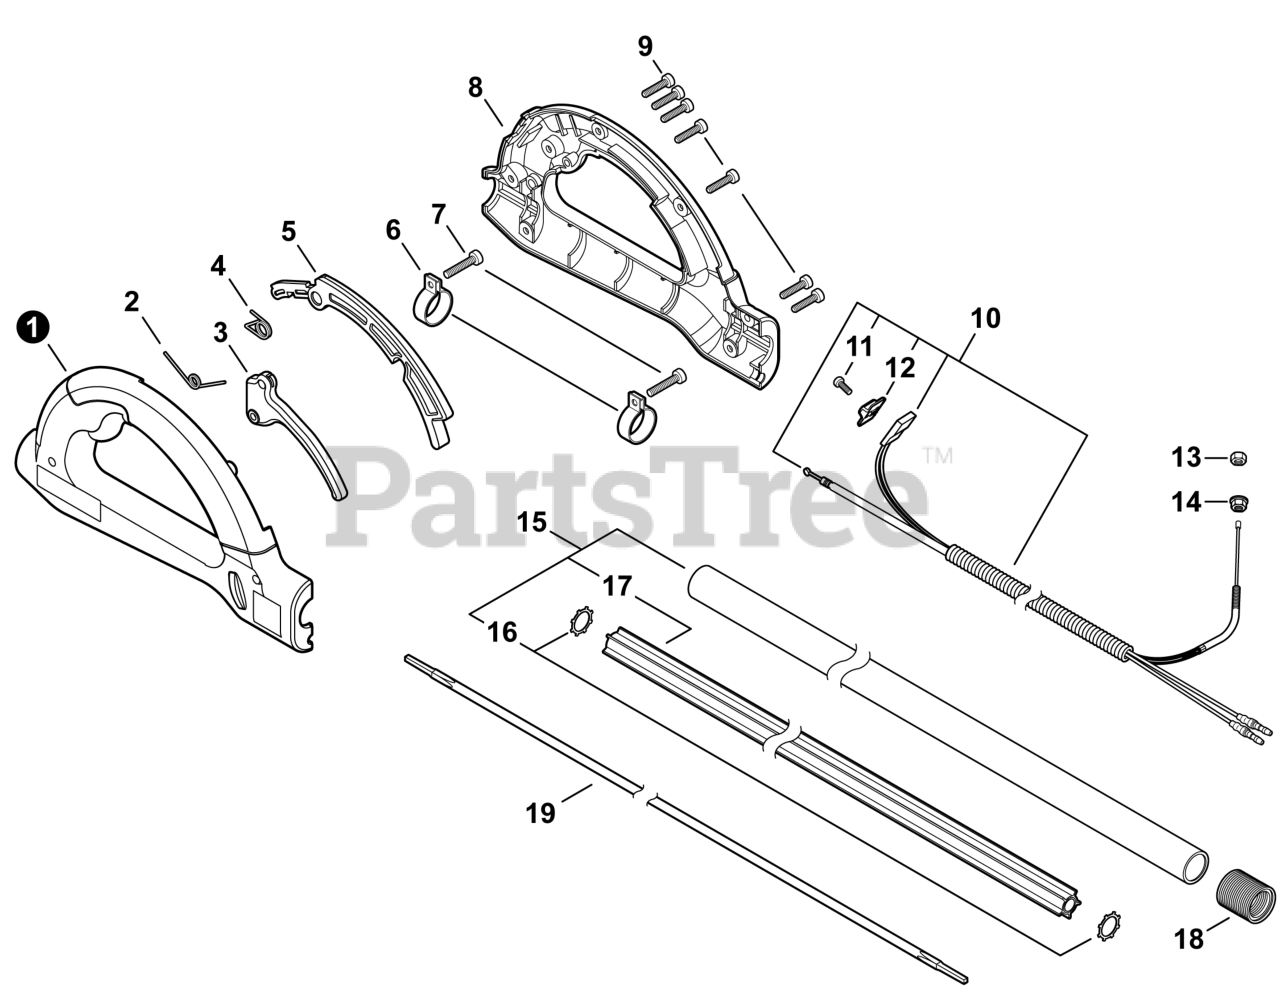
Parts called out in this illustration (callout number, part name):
1	BODY, HANDLE - LEFT
2	SPRING, TORSION
3	TRIGGER, THROTTLE
4	SPRING, TORSION
5	LOCKOUT, THROTTLE
7	BOLT, TORX 5x16
8	BODY, HANDLE - RIGHT
9	BOLT, TORX 5x16
10	CABLE ASSY, CONTROL
11	SCREW 3x10
12	KNOB, SWITCH - ORANGE
14	NUT, FLANGE M6
15	MAIN PIPE ASSY
17	LINER - FLEXIBLE
18	TUBE, FLEXIBLE
19	DRIVESHAFT - FLEXIBLE
